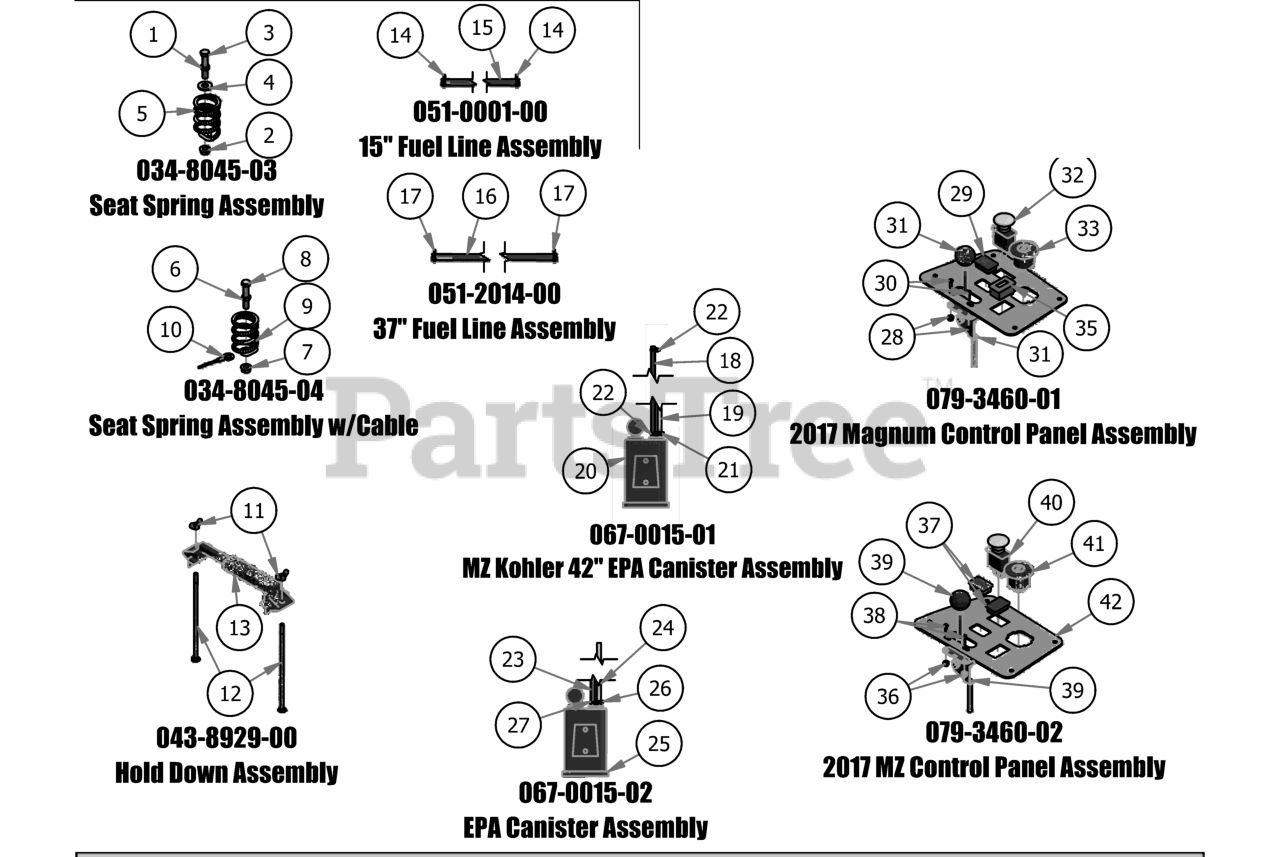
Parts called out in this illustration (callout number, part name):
1	3/8-16 Half Jam Nut
2	3/8" Flange Nut
3	3/8"-16 x 2" Gr 5 Hex Bolt
4	3/8" Flat Washer
5	Seat Spring
6	3/8-16 Half Jam Nut
7	3/8" Flange Nut
8	3/8"-16 x 2" Gr 5 Hex Bolt
9	Seat Spring
10	Seat Cable
11	1/4" Wing Nut
12	1/4-20 X 8 Carriage Bolt
13	Battery Hold Down
14	1/4 Fuel Hose Clamp
15	1/4 Fuel Line
16	37" 1/4 Fuel Line
17	1/4 Fuel Hose Clamp
18	3/16 Vinyl Tubing, 53"
19	3/16" Clear Vinyl Tubing, 44"
20	Carbon Canister for Magnum/MZ
21	3/16" Vinyl Hose Clamp
22	8.6mm Hose Clamp
23	3/16 Vinyl Tubing, 44"
24	3/16" Clear Vinyl Tubing, 52"
25	Carbon Canister for Magnum/MZ
26	3/16" Vinyl Hose Clamp
27	8.6mm Hose Clamp
28	10-24 Nylon Insert Locknut Zinc Orange Nylon
29	Light Plug
30	10-24 X 5/8 BS Button Head Bolt
31	Throttle Lever Assembly
32	PTO Engager
33	Ignition Switch
34	Control Panel
35	Tachometer
36	10-24 Nylon Insert Locknut Zinc Orange Nylon
37	Light Plug
38	10-24 X 5/8 BS Button Head Bolt
39	Throttle Lever Assembly
40	PTO Engager
41	Ignition Switch
42	Control Panel
